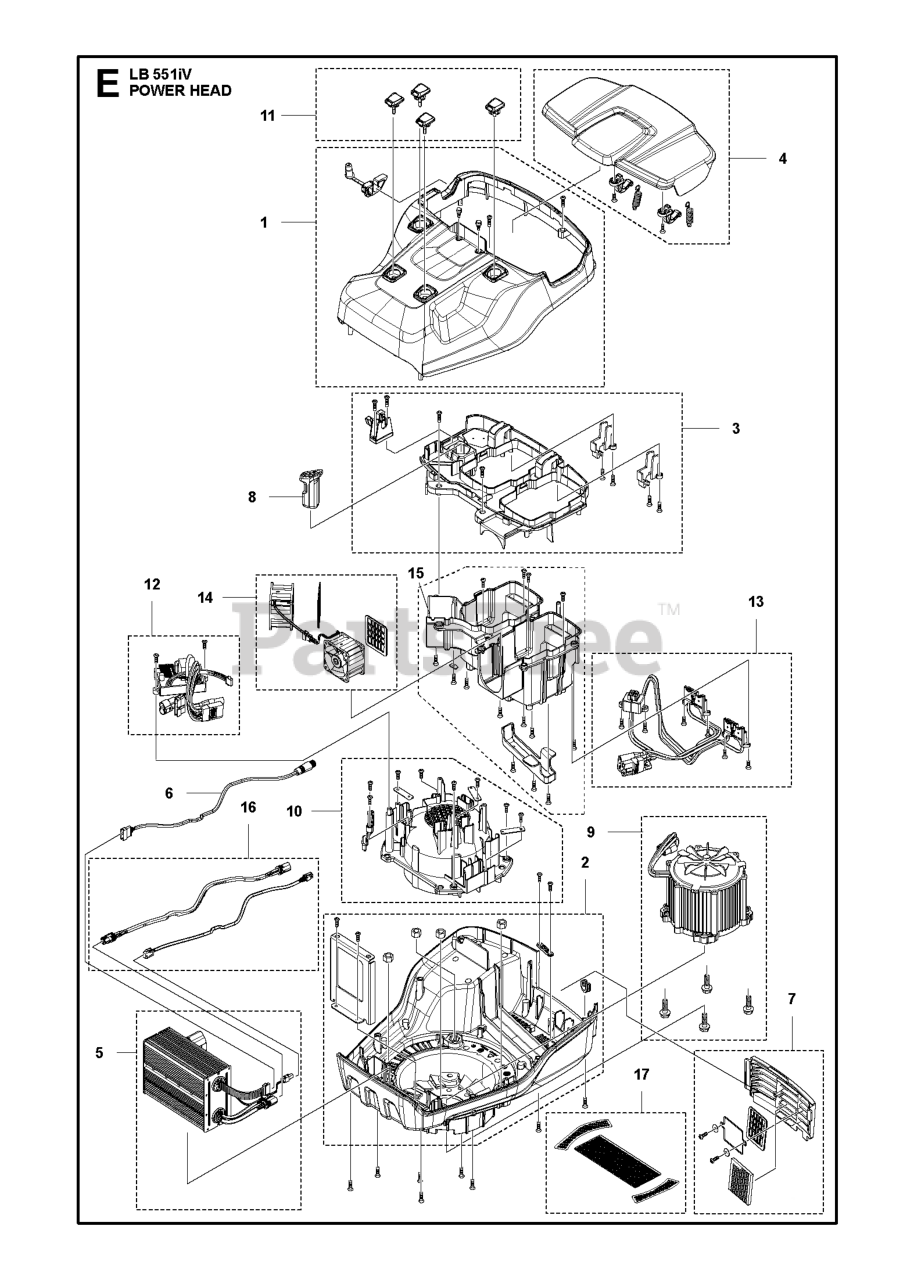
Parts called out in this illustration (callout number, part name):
3	Battery Box
9	Motor
13	Battery Box
14	Battery Box
15	Battery Box
17	COVERS
